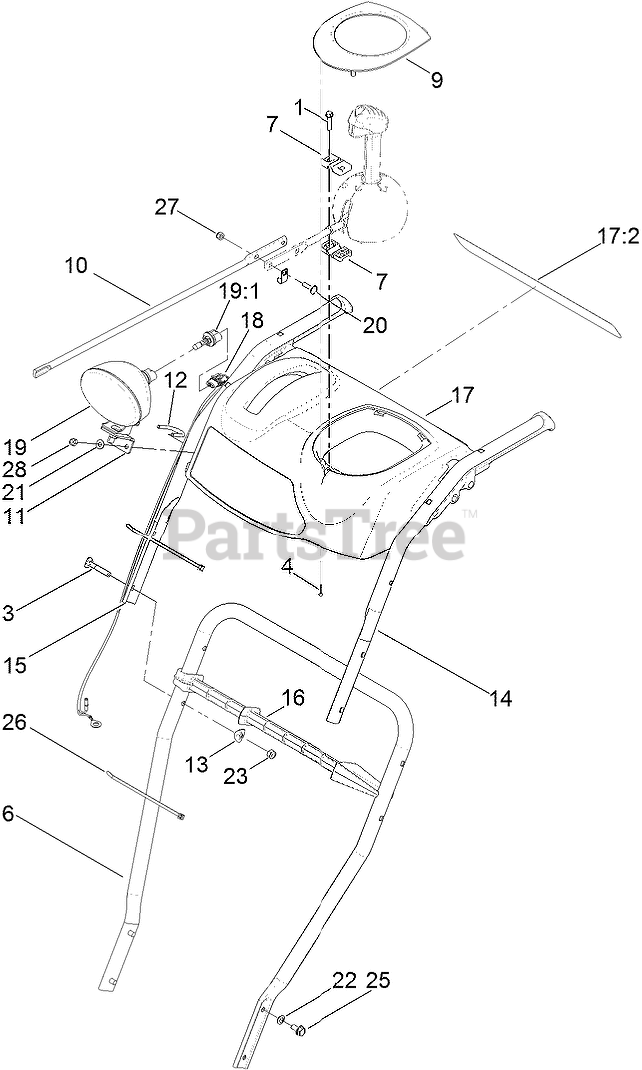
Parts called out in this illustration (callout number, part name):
1	SCREW-PLASTITE
3	SCREW-HANDLE
4	SCREW-PPH
6	HANDLE-LOWER
7	SUPPORT-ROD
9	COVER-PANEL, CONTROL
10	ROD-CHUTE, FRONT
11	BRACKET-LIGHT
12	CLAMP
13	WASHER
14	HANDLE-UPPER, LH
15	HANDLE-UPPER, RH
16	STICK-CLEANOUT
17	CONTROL PANEL ASM
17:2	DECAL-PANEL, CONTROL
18	HARNESS-WIRE, HEADLIGHT
19	HEADLAMP ASM
19:1	LAMP-12 VOLT
20	SCREW-CARR
21	WASHER-FLAT
22	WASHER-BELLEVILLE
23	NUT-LOCK, NI
25	SCREW-HWHTF
26	TIE-CABLE
27	NUT-LOCK, NI
28	NUT-LOCK, NI
